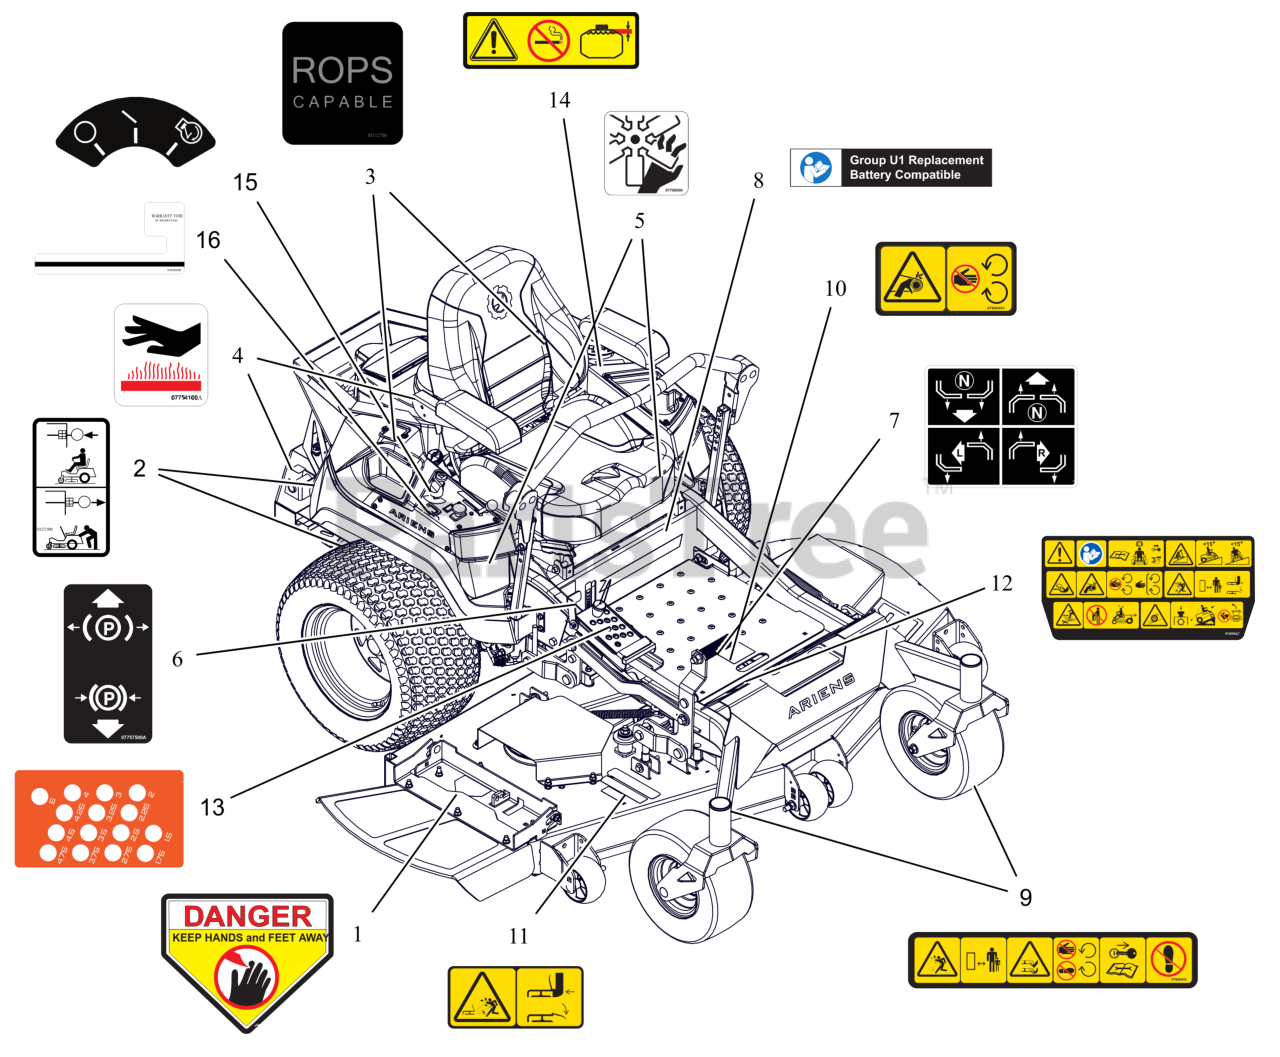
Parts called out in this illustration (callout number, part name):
1	DECAL, DANGER
2	DECAL, TRANSMISSION DISCONNECT
3	DECAL, ROPS LOCATION
4	DECAL, HOT SURFACE
5	DECAL, DANGER FAN
6	DECAL, PARKING BRAKE LEVER
7	DECAL, INSTRUCTIONAL-STEERING
8	DECAL, U1 BATTERY REPLACEMENT
9	DECAL, DECK SAFETY
10	DECAL, SAFETY - GUARDING
11	DECAL, SAFETY - DECK GUARDING
12	DECAL, MAIN SAFETY
13	DECAL, ARIENS HOC
14	DECAL, FUEL WARNING
15	DECAL, KEYSWITCH
16	DECAL,HOURMETER - SECURITY
